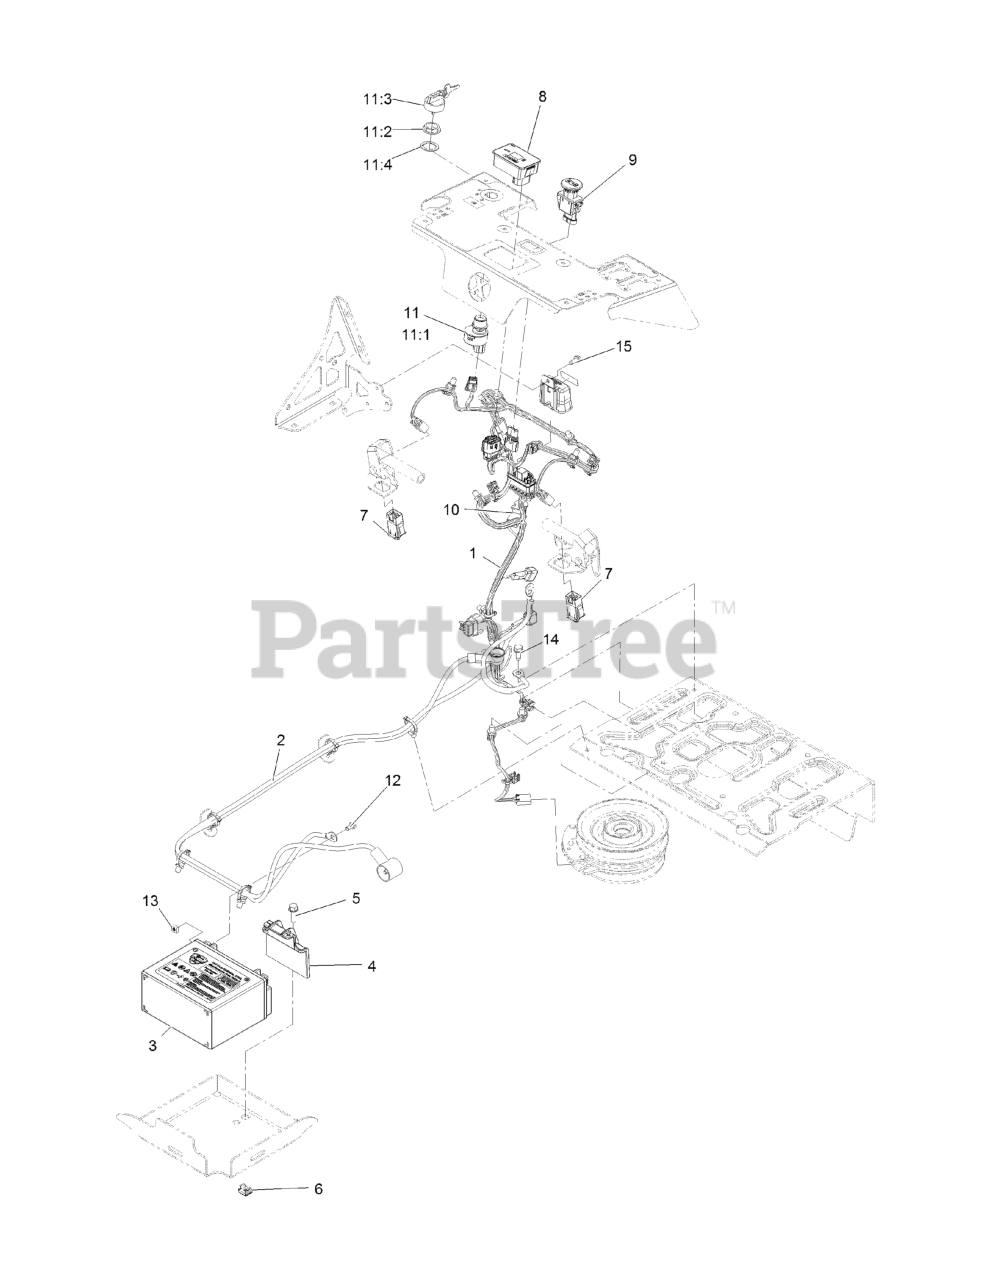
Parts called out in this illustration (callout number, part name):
2	HARNESS-BATTERY
3	BATTERY, AGM, NON-SPILLABLE
4	HOLD DOWN, BATTERY
5	SCREW-HHF
6	NUT, SNAP
7	SWITCH-DELTA
8	Module-Hour Meter
9	SWITCH-PTO, SEALED
10	SWITCH-BAIL
11	IGNITION SWITCH ASM
11:1	Switch-Ignition
11:2	NUT-MOUNTING
11:3	IGNITION KEY SET
11:4	WASHER-BACKUP
14	SCREW-THD ROLL, HWH
15	SCREW-HWH
16	WASHER-SPRING
